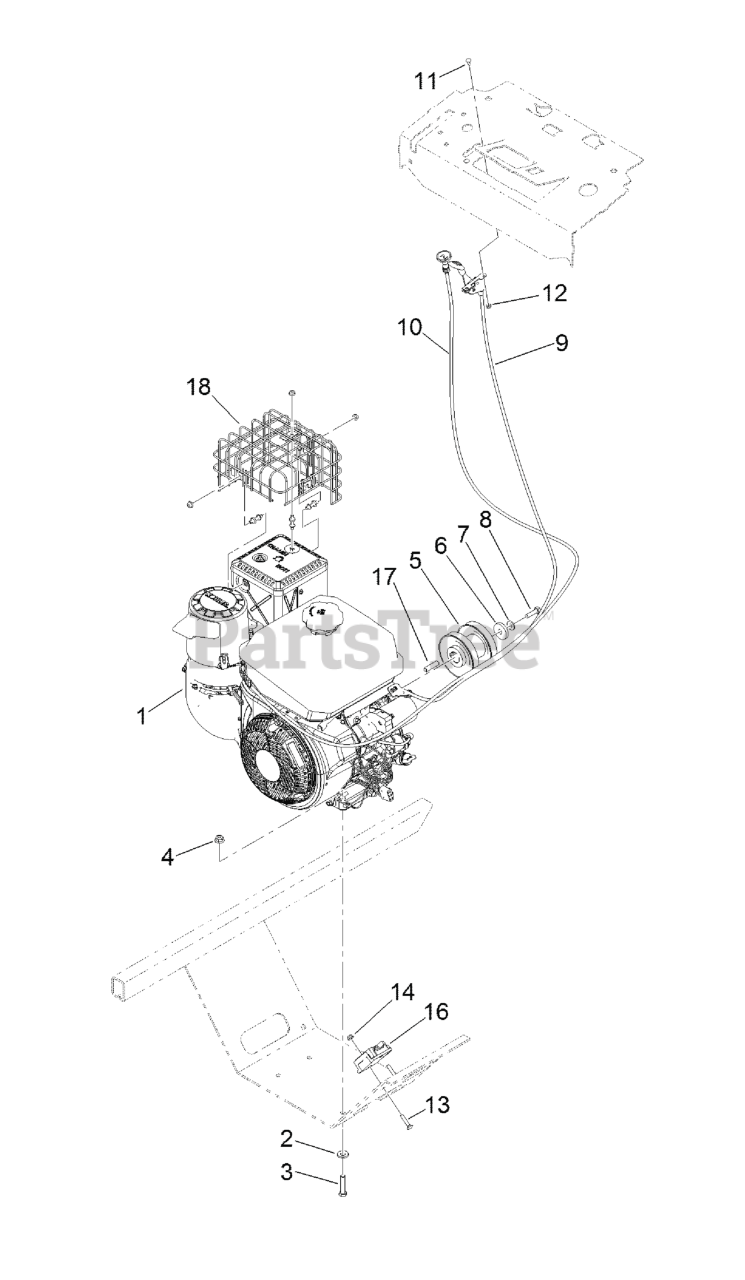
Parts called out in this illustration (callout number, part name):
1	ENGINE-KOHLER, CH440-3041
2	WASHER-BELLEVILLE
3	SCREW-HH
4	NUT-HF, NI
6	WASHER-CLUTCH
7	WASHER-SPRING
8	SCREW-HH
9	CONTROL-THROTTLE
10	CABLE-CHOKE, PUSH/PULL
11	BOLT-CARR
12	NUT-LOCK, NI
13	SCREW-CARR
16	REGULATOR
17	KEY-SQUARE, 7MM
18	KIT-MUFFLER BIRDCAGE
